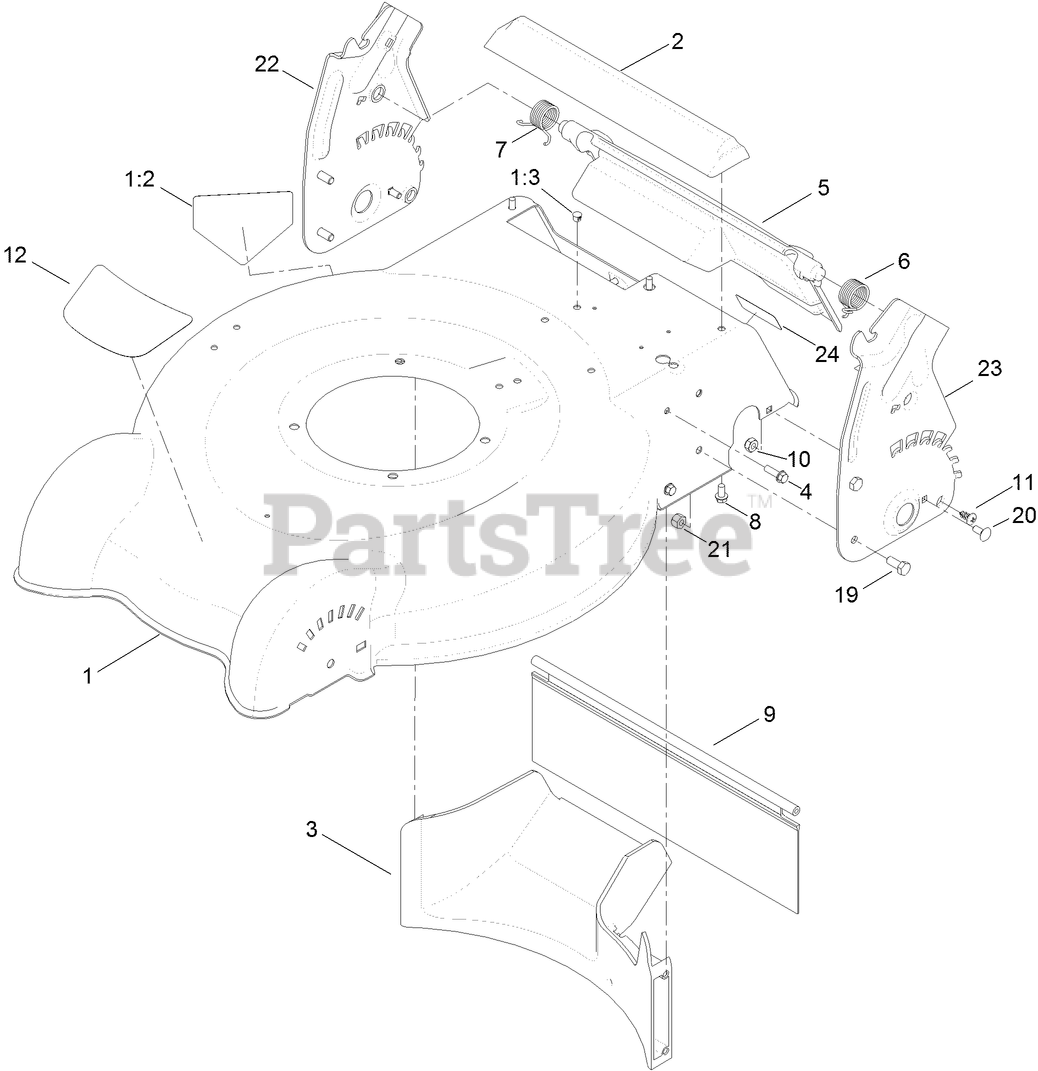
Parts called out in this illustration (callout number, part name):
1	HOUSING ASM
1:2	DECAL-DANGER
1:3	PLUG-DOME
2	CHUTE-REAR
3	BAFFLE-REAR
4	SCREW-HWH
5	REAR DEFLECTOR ASM
6	SPRING-TORSION, LH
7	SPRING-TORSION, RH
8	SCREW-PLASTITE
9	SHIELD-TRAILING
10	NUT-LOCK, NI
11	SCREW-PTH
12	DECAL-DECK
19	SCREW-HH
20	SCREW-CARR
21	NUT-LOCK, NI
22	PLATE-HOC, LH
23	PLATE-HOC, RH
24	DECAL-LOCATION, SERVICE DEALER
